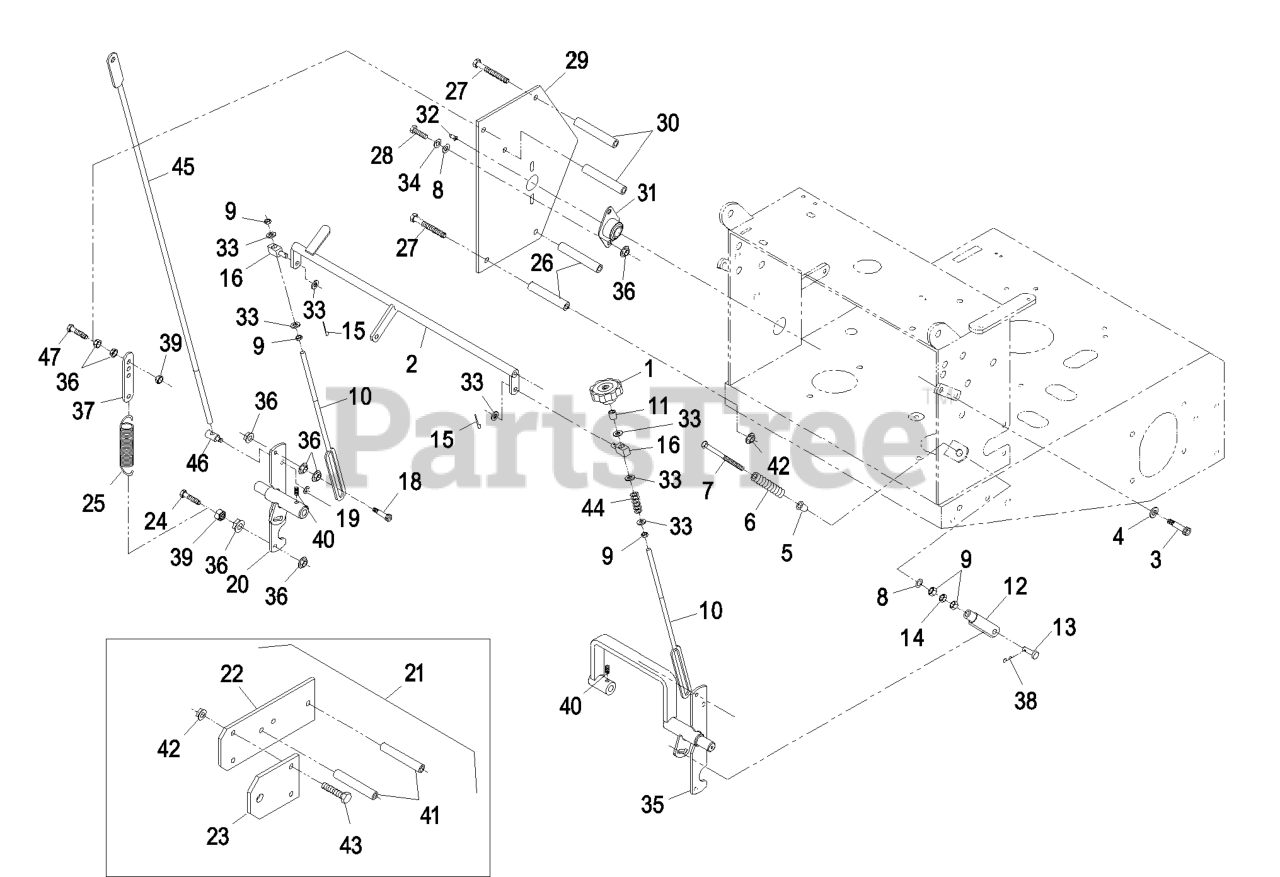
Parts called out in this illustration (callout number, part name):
1	KNOB-TRACKING
2	CRANK-CONTROL, SPEED
3	SCREW-HSH
5	BUSHING-FLANGED
6	SPRING-RETURN, NEUTRAL
7	BOLT-RETURN, NEUTRAL
10	LINK-CONTROL, SPEED
12	YOKE-ADJUSTABLE
13	PIN-CLEVIS
18	SCREW-HH
21	Sulky Hitch Kit, (Vik Hydro)
22	MOUNT-HITCH
23	Bracket, Hitch Adapter
25	SPRING-EXTENSION
26	SPACER-SHIELD
30	SPACER-SHIELD
31	BEARING-FLANGE, SIDE
34	WASHER-LOCK
37	TAB-SPRING, EXTENSION
38	PIN-COTTER
40	SCREW-SET
44	SPRING-COMPRESSION
45	ROD-LEVER, DRIVE
47	BOLT-TAP, HH
